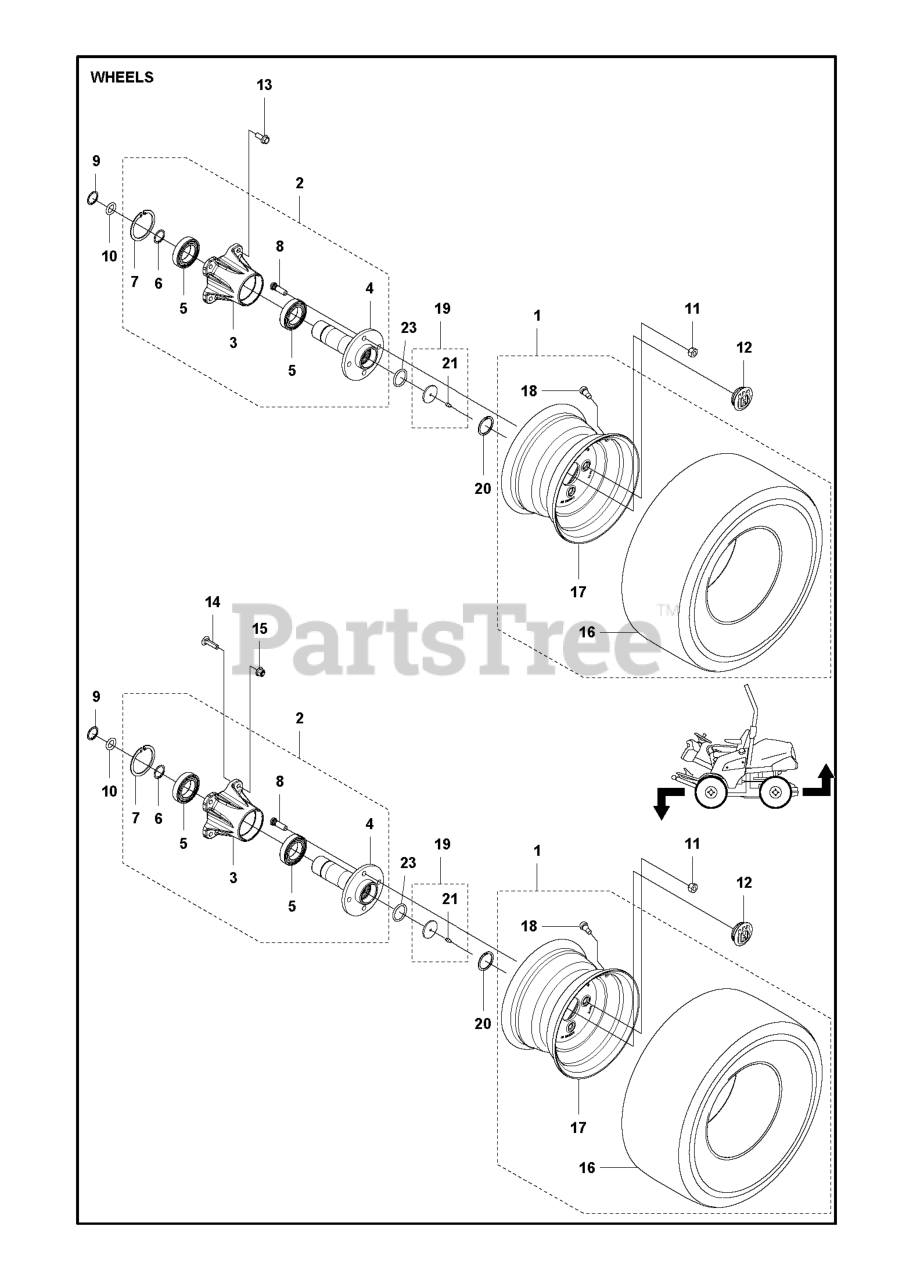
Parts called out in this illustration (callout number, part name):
9	RETAINING RING
18	VALVE
21	GREASE NIPPLE
